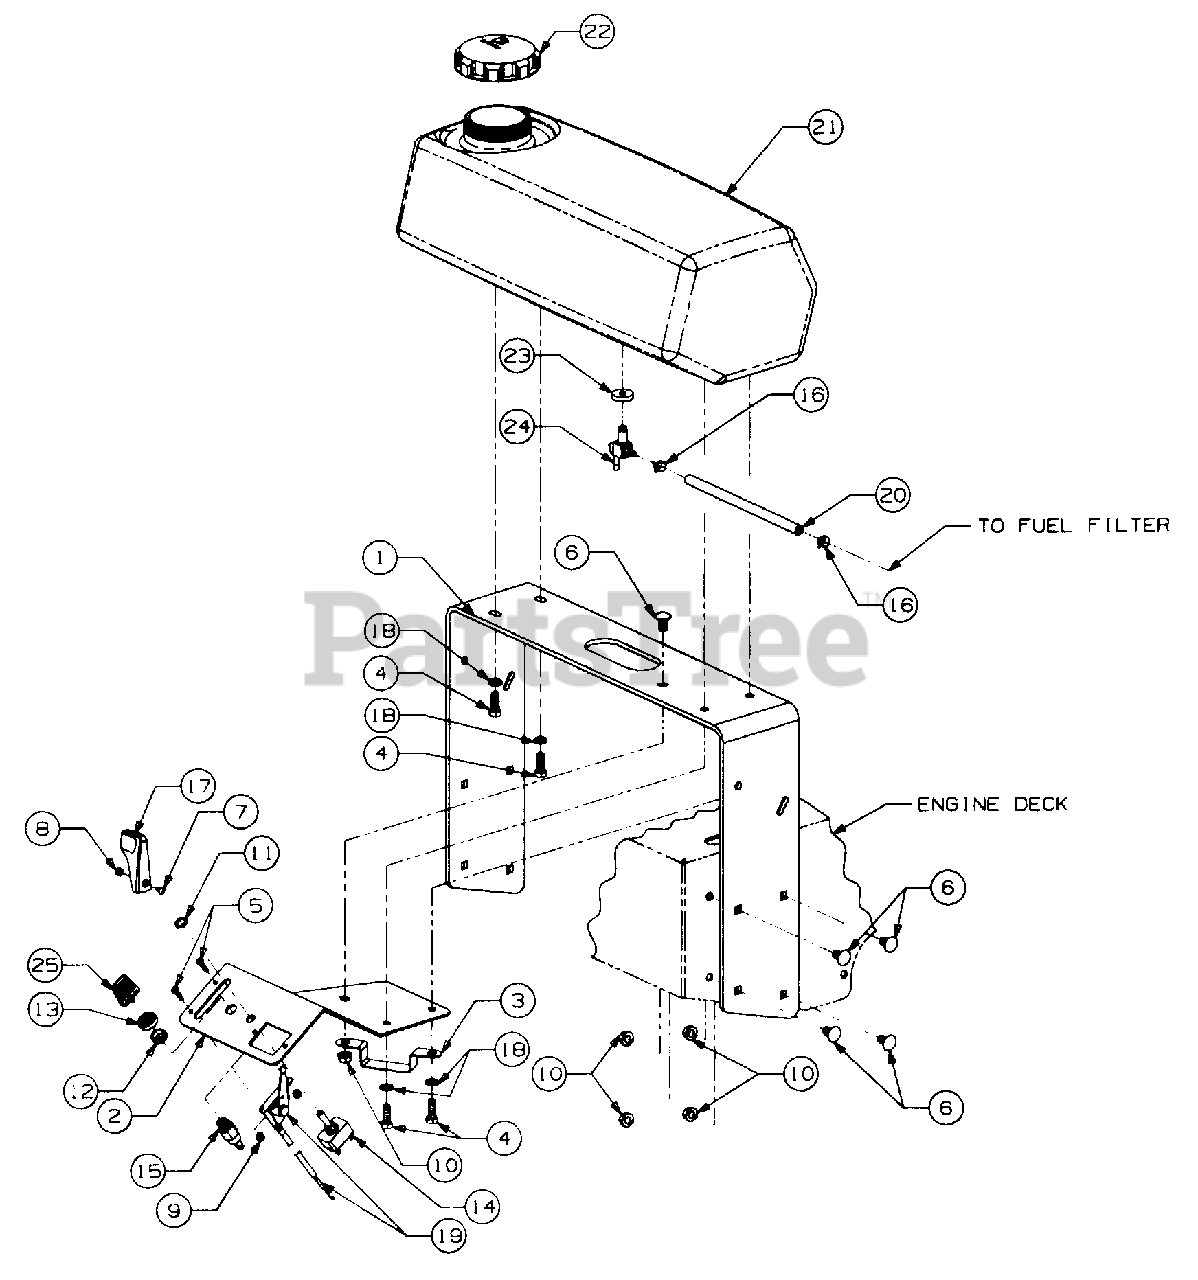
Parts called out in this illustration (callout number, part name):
1	Support, Lower Handle
2	Panel, Control
3	Bracket, Cable Retainer
4	Screw, Hex Cap, 3/8-16 X 1.0 Lg GR5
5	Screw, Pan hd Cutting, #10-24 X .75 Lg
6	Bolt, Sht Nk Carriage, 3/8-16 X .75 Lg GR5
7	Screw, Cross Rec Truss Hd, #8-32 X .38 Lg
8	Nut, Hex, #8-32
9	Nut, Hex Nylock, #10-24
10	Nut, Hex Flanged Lock, 3/8-16
11	Nut, Hex, 1/2-27 X .100 Thk
12	Nut, Ignition Switch, 5/8-32
13	Cap, Ignition Switch
14	Switch, PTO
15	Switch, Ignition
16	Clamp, Hose
17	Knob, Throttle Control
18	Washer, Lock, 3/8
19	Control, Throttle
20	Line, Fuel - 15" Lg
21	Tank, Fuel
22	Cap, Fuel
23	Grommet, Shutoff Valve
24	Valve, Fuel Shutoff
25	Key, Ignition
